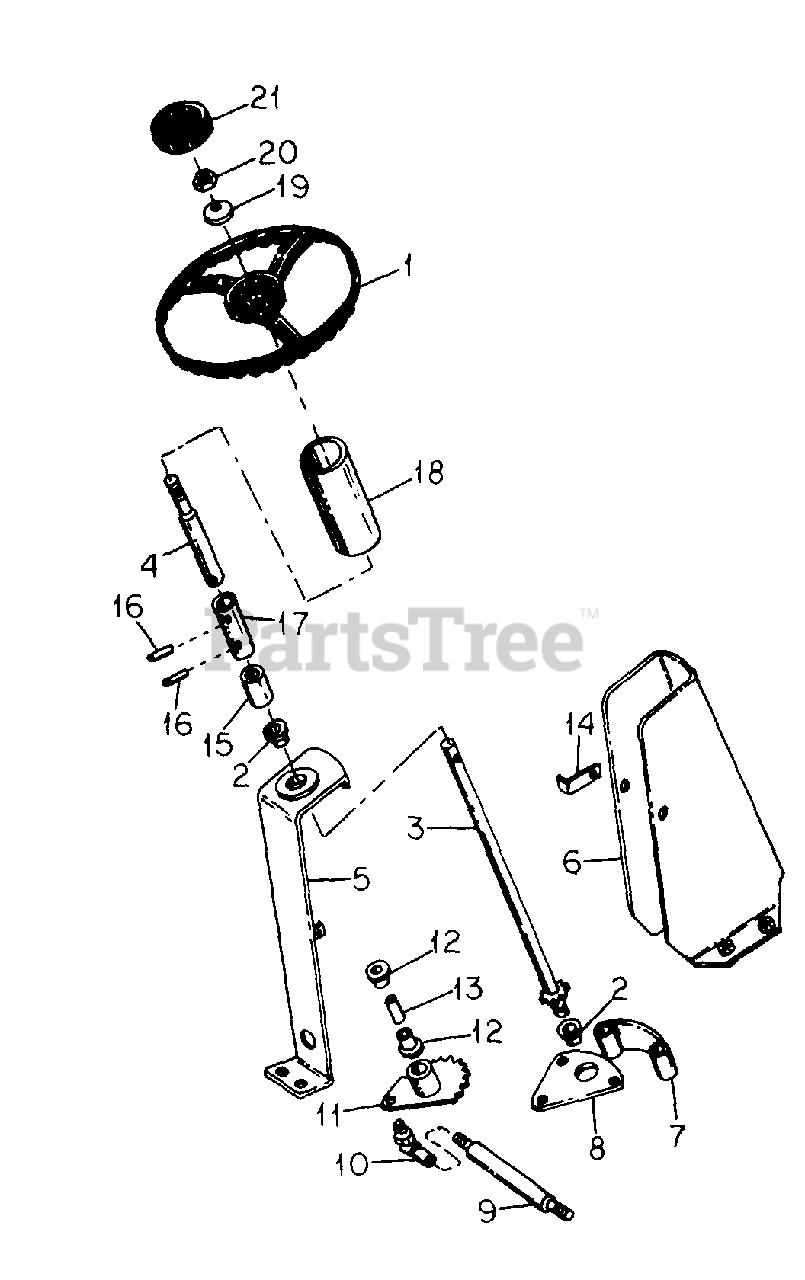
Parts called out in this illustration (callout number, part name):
1	WHEEL, STEERING
2	BEARING, STEERING SHAFT
3	SHAFT ASSY, LOWER STEERING
4	SHAFT, UPPER STEERING
5	SUPPORT ASSY. STEERING
6	SHROUD ASSY, STEERING SUPPORT
7	COVER, FRT STEERING GEAR
8	COVER ASSY, STEERING GEAR
9	STUD, DRAG LINK ROD
10	JOINT 3/8 C-Z TYPE G BALL
11	GEAR ASSY, STEERING DRAG LINK
12	BEARING, STEERING GEAR
13	BUSHING. STEERING GEAR DRAG LINK
15	SPACER, STEERING SHAFT
16	PIN, 1/4 X 1-3/8 MED PLN CLD SPR
17	BUSHING, SHAFT SLEEVE
18	SPACER. STEERING TUBE
19	WASHER, BELLEVILLE
20	NUT, 5/16 CAD P/T LOCK TYPE 5
21	CAP, STEERING WHEEL
